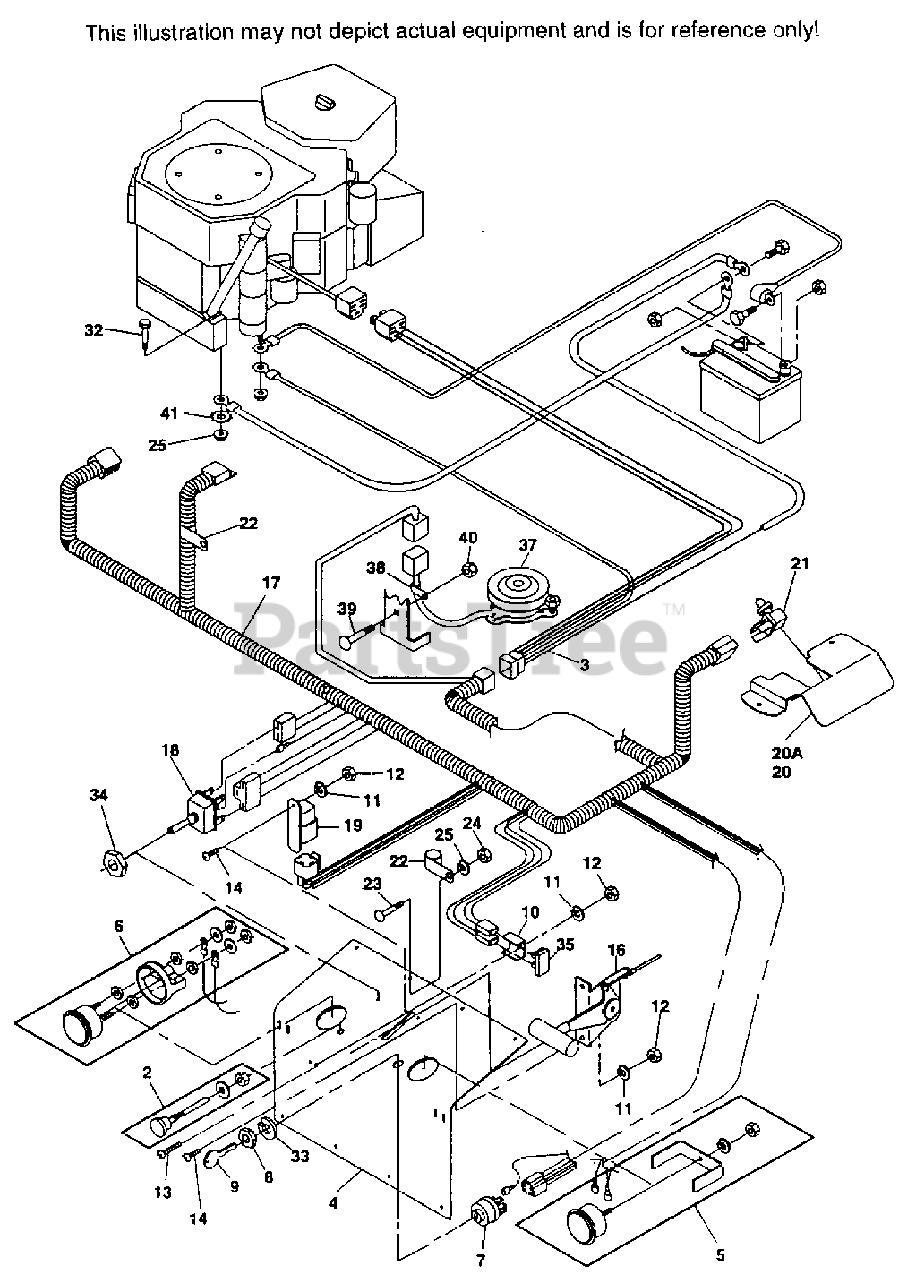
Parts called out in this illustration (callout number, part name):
2	CHOKE CONTROL
3	ADAPTER
4	KICK PLATE
5	HOUR METER
6	AMMETER
7	KEY SWITCH(INCLUDES MOUNTING HARDWARE)
8	HEX NUT, 5/8-32"
9	KEY & RING ASSEMBLY
10	BRACKET, FUSE HOLDER
11	LOCKWASHER #10 EXTERNAL TOOTH
15	OVERFLOW TUBE
16	THROTTLE CONTROL
17	WIRE HARNESS
18	SWITCH, MOWER ENGAGEMENT ELECTRIC CLUTCH
19	RELAY
20	NEUTRAL LOCK BRACKET, RH
20A	NEUTRAL LOCK BRACKET, LH
21	SWITCH NEUTRAL LOCK
25	NUT, 5/16-18 SERRATED FLANGE HEX HEAD
26	BATTERY
29	RUBBER BOOT
31	BATTERY CABLE, 27" BLACK
32	CAP SCREW, 5/16-18 X 1-1/2" SERRATED
33	LOCKWASHER, 5/8" INTERNAL
34	HEX NUT, 1/2-27
35	BLADE TYPE FUSE, 20 AMP
36	ELASTIC STOP NUT # 10-32
37	ELECTRIC CLUTCH
40	ELASTIC STOP NUT, 5/16-18
41	LOCKWASHER, 5/16" INTERNAL TOOTH
